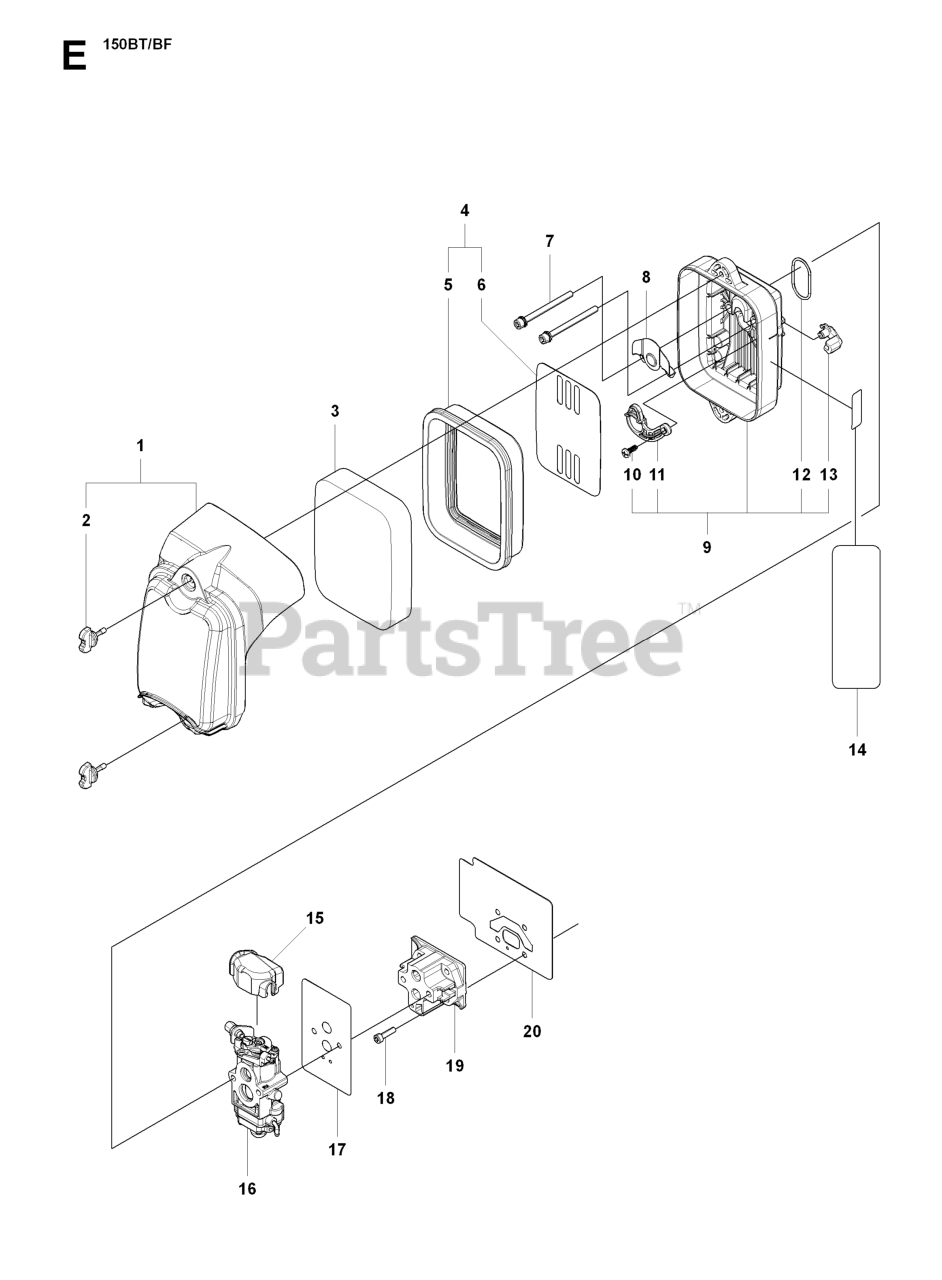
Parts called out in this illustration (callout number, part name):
3	AIR FILTER
9	CARBURETOR BODY
14	RP_LABEL, HOTMARK
15	COVER
16	CARBURETOR
18	BOLT
19	INSULATION
20	RP INSULATOR GASKET
